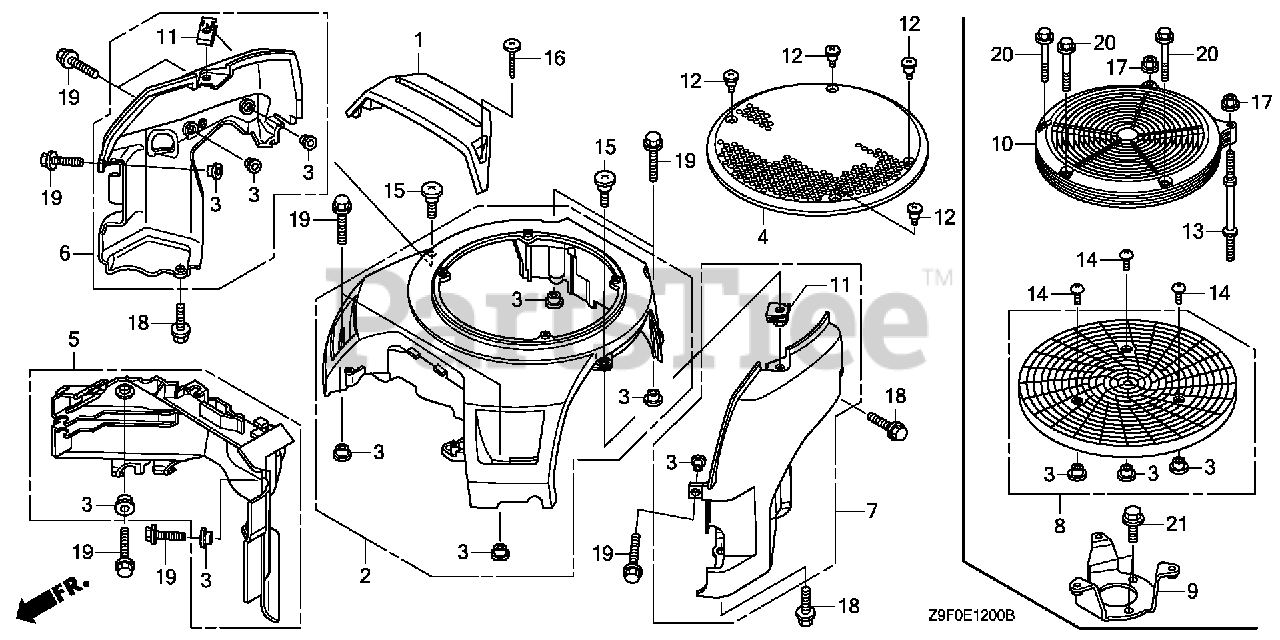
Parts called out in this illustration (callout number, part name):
1	COVER, FUEL PUMP
2	COVER, FAN *R280* (POWER RED)
2	COVER, FAN *NH1* (BLACK)
3	COLLAR, FAN COVER
5	SHROUD (UPPER)
6	SHROUD, R. (LOWER)
7	SHROUD, L. (LOWER)
8	GRID, SCREEN
9	HOLDER, SCREEN GRID
10	COVER, SCREEN GRID
11	NUT, FENDER SETTING
13	BOLT, STUD
14	SCREW, TRUSS (6X16)
15	SCREW, SPECIAL (6X15)
16	SCREW, TAPPING (5X20)
17	NUT, FLANGE (6MM)
18	BOLT, FLANGE (6X16)
19	BOLT, FLANGE (6X20)
20	BOLT, FLANGE (6X40)
21	BOLT, FLANGE (8X18)
